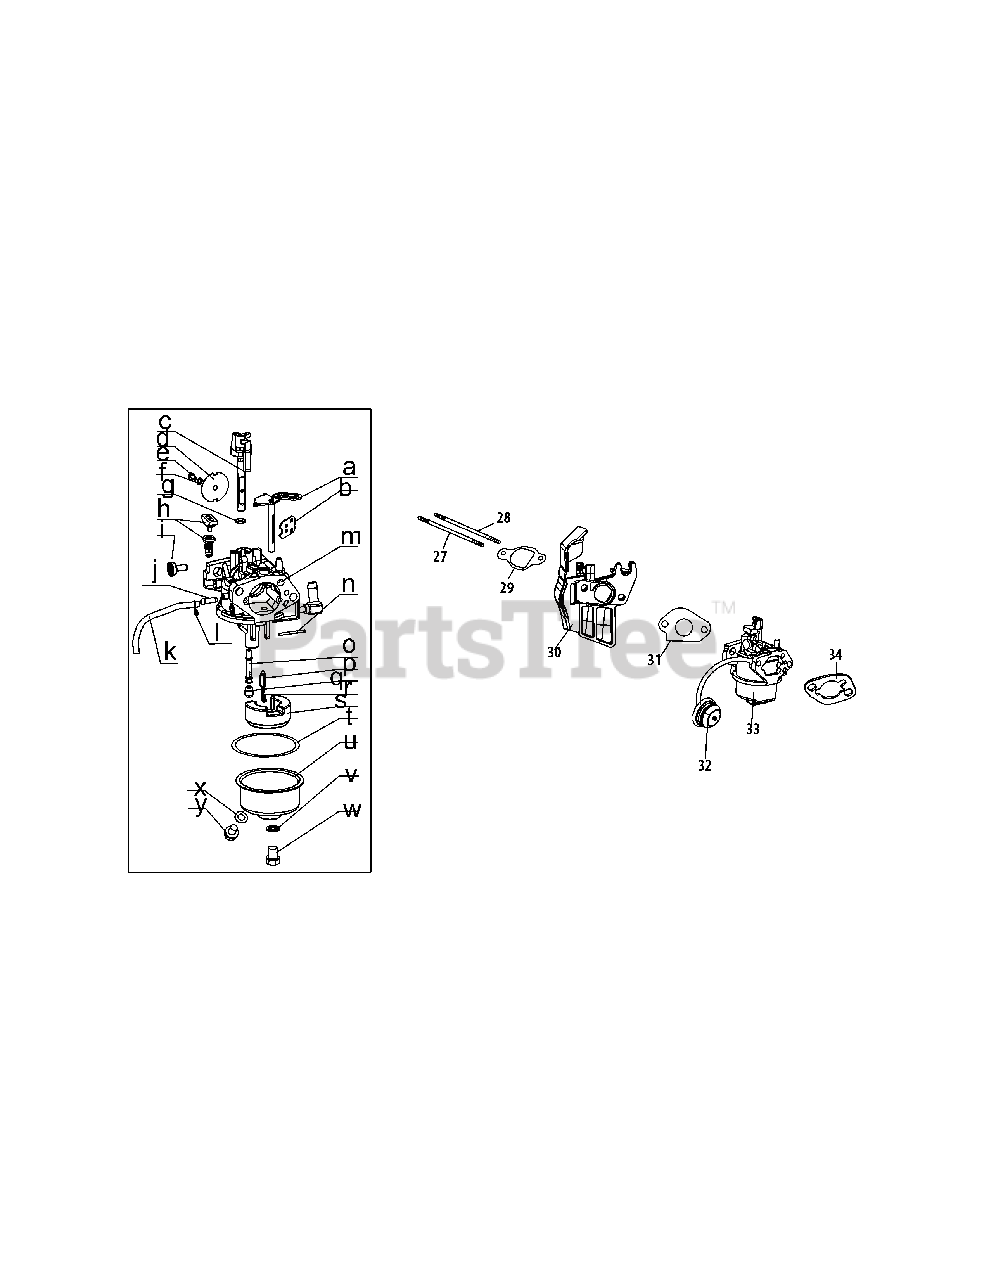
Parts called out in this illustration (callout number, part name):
27	Stud M6×117
28	Stud M6×105
29	Carburetor Insulator Gasket
30	Carburetor Insulator
31	Carburetor Gasket
32	Primer Assembly
32	Primer Bulb
33	Carburetor Assembly
34	Carburetor Gasket Plate
